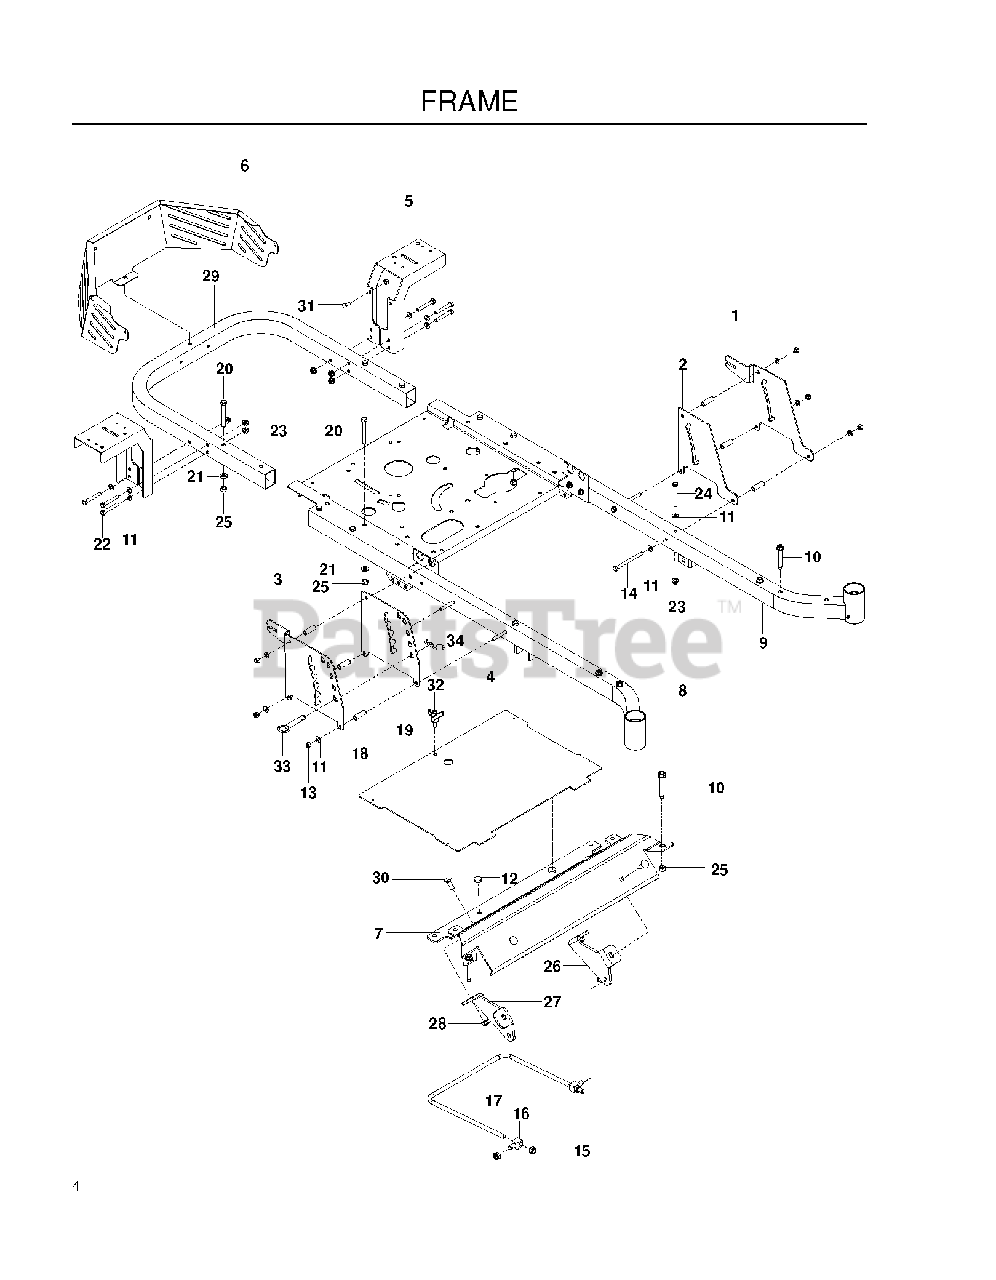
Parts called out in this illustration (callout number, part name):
1	PLATE, OUTER BRAKE, BLACK
2	PLATE, BRAKE LATCH, BLACK
4	PLATE, FOOT W/DECALS KZ
5	SUPPORT, FENDER, BLACK
6	GUARD, REAR, BLUE
7	FOOT REST, WIDE, BLUE
8	FRAME, RT, BLUE
9	FRAME, LT, BLUE
10	ENGINE BOLT, SPECIAL
11	FLAT WASHER 5/16 SAE
12	GROMMET, BUMPER
13	NUT 5/16 NYLOC
14	HCS 5/16C X 4
15	7/16-14 HEX NUT W/NYL RING ZD
17	LINK, FRONT SUSP.
18	SPACER, .334 ID X .5 OD X 1.5
19	PLATE, DECK HEIGHT, BLACK
20	HCS 3/8C X 3
21	WASHER 3/8 SAE FLAT
22	CAPSCREW
23	5/16-18 NYLOC FLANGE NUT
24	HCS 5/16C X 2-3/4
25	NUT 3/8-16 NYLOC
26	MOUNT, STRUT, RT, BLK
27	MOUNT, STRUT, LT, BLK
28	NUT 3/8-16 HEX FLG NYLOC ZD
29	FRAME TUBE, REAR BLUE
30	RHSNB 3/8C X 1
31	BOLT 5/16C X 3/4" CARRIAGE
32	KNOB W/STUD
33	HITCH PIN
34	HAIRPIN #4
